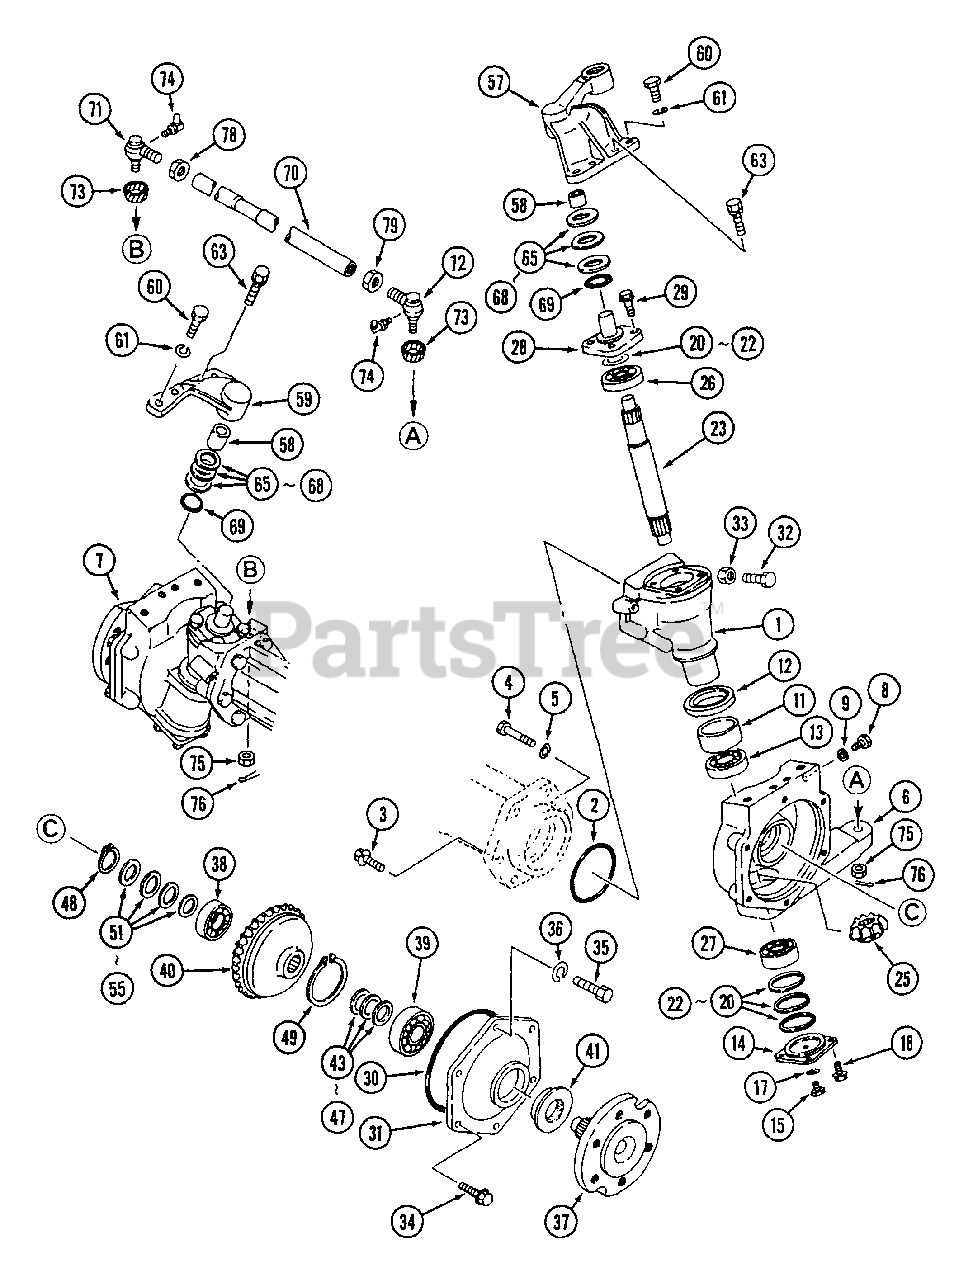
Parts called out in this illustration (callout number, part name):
1	Case, Kingpin
6	Case, Final L.H.
7	Case, Final R.H.
20	Liner, t=0.15
21	Liner, t=0.2
22	Liner,t=0.3
40	Gear, 32T
43	Liner, t=0.15
44	Liner, t=0.4
45	Liner, t=0.8
46	Liner, t=1.0
47	Liner, t=1.2
51	Liner
52	Liner, t=0.4
53	Liner, t=0.8
54	Liner, t=1.0
55	Liner, t=1.2
57	Knuckle, Arm L.H.
59	Knuckle, Arm R.H.
65	Liner, Thrust
66	Liner, Thrust
67	Liner, Thrust
68	Liner, Thrust
71	Rod End Ass’y., R.H. (LH thread) Includes Ref. Nos. 73-76
72	Rod End Ass’y., L.H. (RH thread) Includes Ref. Nos. 73-76
73	Cover, Dust (use with MA-67441-00900 & MA-67441-01000 Rod End Ass’ys)
73	Cover, Dust (use with MA-10302157AG0 & MA-10302158AG0 Rod End Ass’ys)
74	Nipple, Grease (use with MA- 67441-00900 & MA-67441-01000 Rod End Ass’ys)
74	Nipple, Grease (use with MA-10302157AG0 & MA-10302158AG0 Rod End Ass’ys)
75	Nut (use with MA-67441-00900 & MA-67441-01000 Rod End Ass’ys)
75	Nut (use with MA-10302157AG0 & MA-10302158AG0 Rod End Ass’ys)
76	Pin, Split (use with MA-67441- 00900 & MA-67441-01000 Rod End Ass’ys)
76	Pin, Split (use with MA-10302157AG0 & MA-10302158AG0 Rod End Ass’ys)
78	Nut (LH thread)
79	Nut (RH thread)
